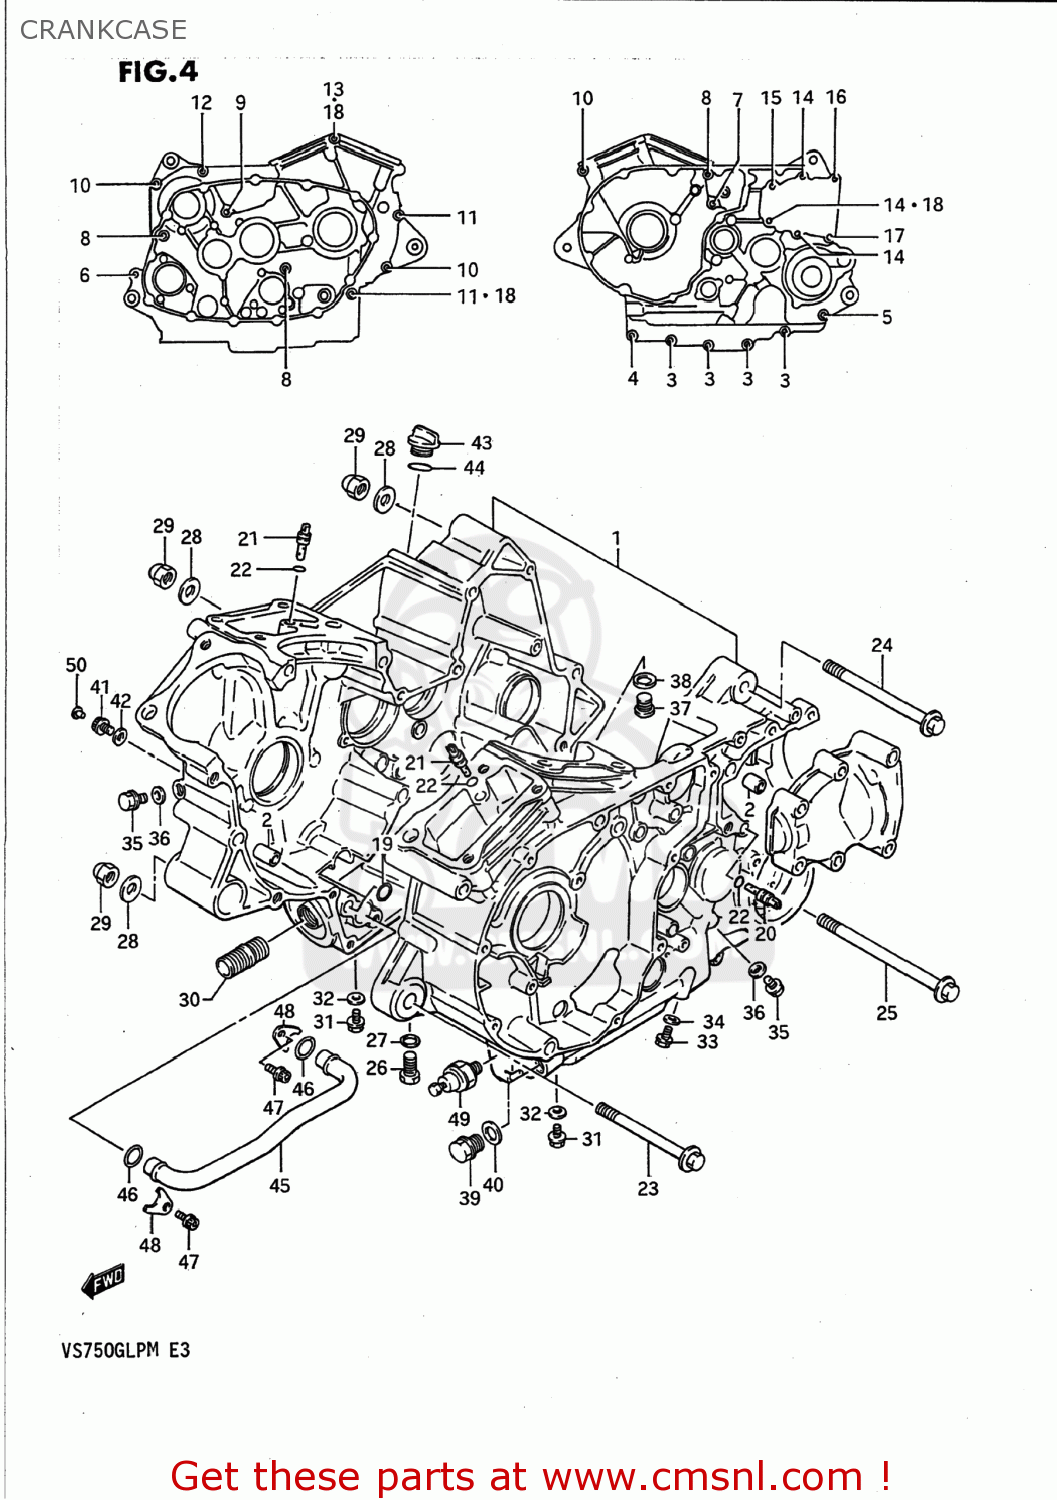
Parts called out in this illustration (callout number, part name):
1	CRANKCASE SET
2	PIN (11X20)(SUS)
3	BOLT
4	BOLT
5	BOLT 8X55
6	BOLT
7	BOLT 8X75
8	BOLT (8X95)
9	BOLT(8X120)
10	BOLT(8X95)
11	BOLT(8X105)
12	BOLT(8X120)
13	BOLT(8X160)
14	BOLT (8X40)
15	BOLT
16	BOLT(8X55)
17	BOLT(8X65)
18	GASKET 8.2X14X1 (NAS)
19	O-RING
20	JET,OIL GALLERY
21	JET,AIR(14)
22	O RING(D:1.2,ID:4)
23	BOLT(10X125)
24	BOLT
25	BOLT(10X150)
26	BOLT
27	GASKET(12.1X16.2X3.7) (NAS)
28	WASHER 10MM
29	NUT
30	UNION,OIL STAND
31	BOLT 8X12
32	GASKET(8.2X14X1).6 (NAS)
33	PLUG
34	GASKET(10X14X3.6) (NAS)
35	BOLT
36	GASKET(5.8X13X1.2) (NAS)
37	PLUG
38	GASKET(16X22X2) (NAS)
39	PLUG (14X12)
40	GASKET(14X19.2X2) (NAS)
41	BOLT
42	GASKET(8.2X14X1).6 (NAS)
43	PLUG
44	O RING(D:3.1,ID:16.8)
45	PIPE,OIL GALLERY
46	O RING(D:3.1,ID:14.8)
47	BOLT
48	CLAMP,OIL PIPE
49	SWITCH ASSEMBLY
50	CAP(OD:11)
